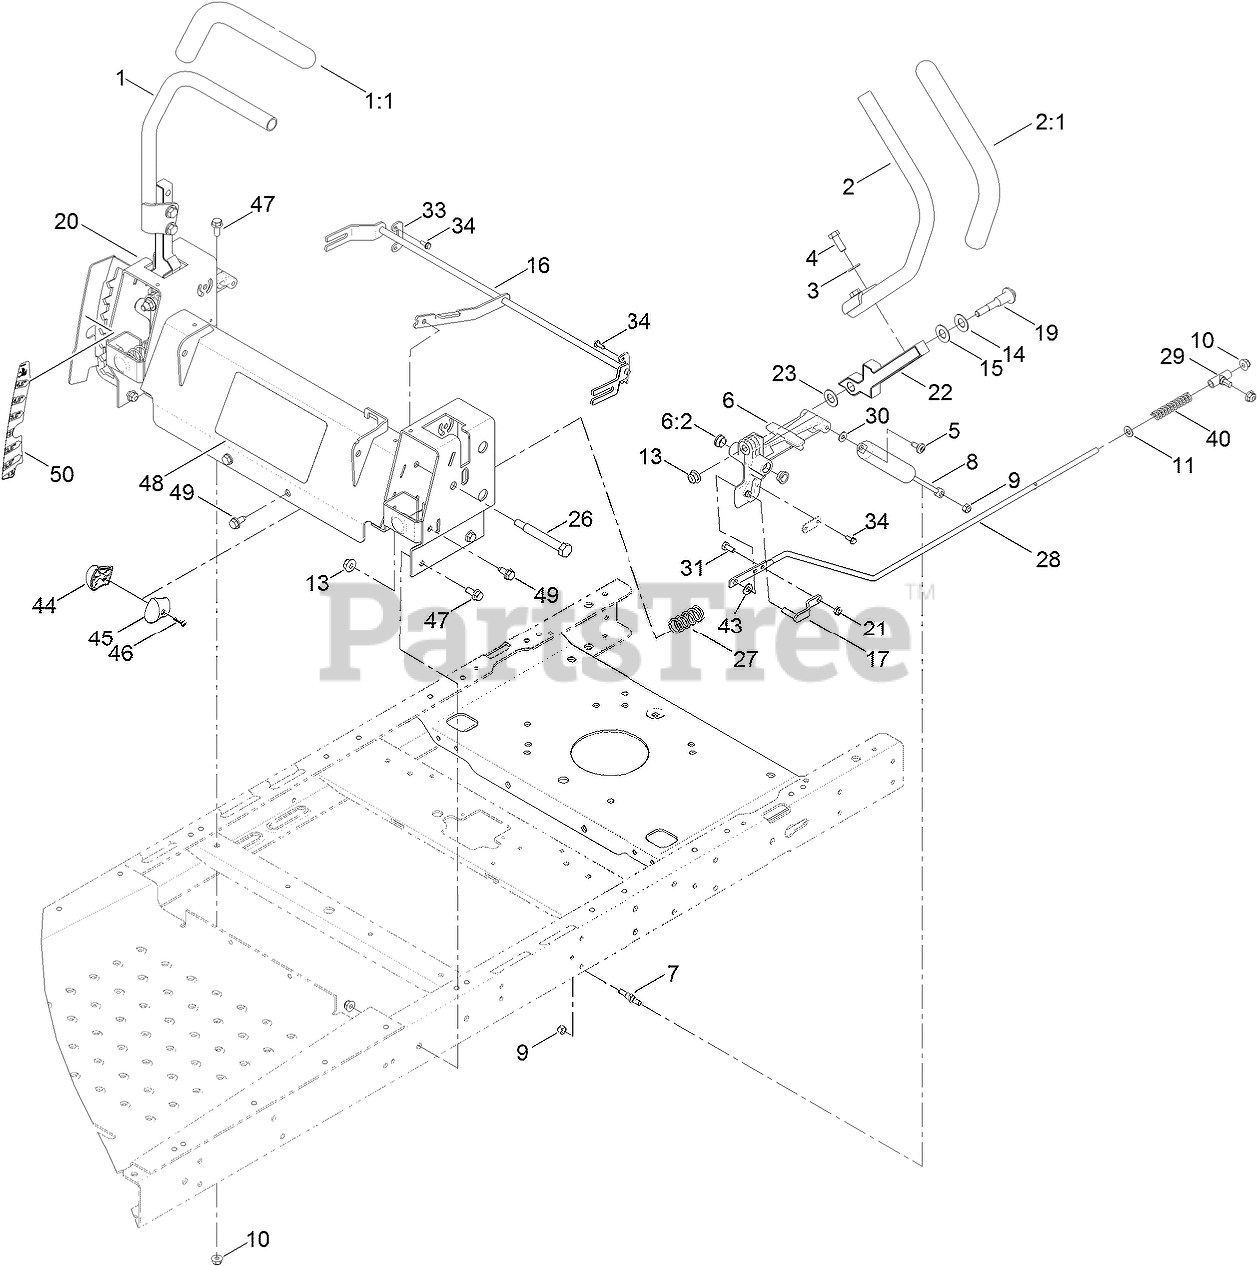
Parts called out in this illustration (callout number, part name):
1	HANDLE-CONTROL, RH
2	HANDLE-CONTROL, LH
3	WASHER-FLAT
4	SCREW-HH
5	SCREW-SHOULDER
6	ACTUATOR ARM ASM
6:2	BUSHING-FLANGE
7	STUD-DAMPER
8	DAMPER
9	NUT-LOCK, NI
10	NUT-HF, NI
11	WASHER-PLAIN
13	NUT-HF, NI
14	WASHER-BELLEVILLE
15	WASHER
16	SPEED CONTROL ASM
17	PIN-ROD, HYDRO
19	BOLT-PIVOT
20	CONTROL BOX ASM
21	NUT-LOCK, NI
22	LEVER-CONTROL
23	WASHER-NYLON
26	BOLT-PIVOT
27	SPRING-RETURN
28	ROD-HYDRO
29	MOUNT-ROD, HYDRO
30	WASHER
31	SCREW-HH
33	RETAINER
34	SCREW-TAPTITE
40	SPRING-RETURN, NEUTRAL
43	SPACER-NYLON
44	KNOB-RH
45	KNOB-LH
46	SCREW-PPH
47	SCREW-HHF
48	DECAL-CONTROL, SPEED
49	SCREW-HWHTF
50	DECAL-HOC, CE
